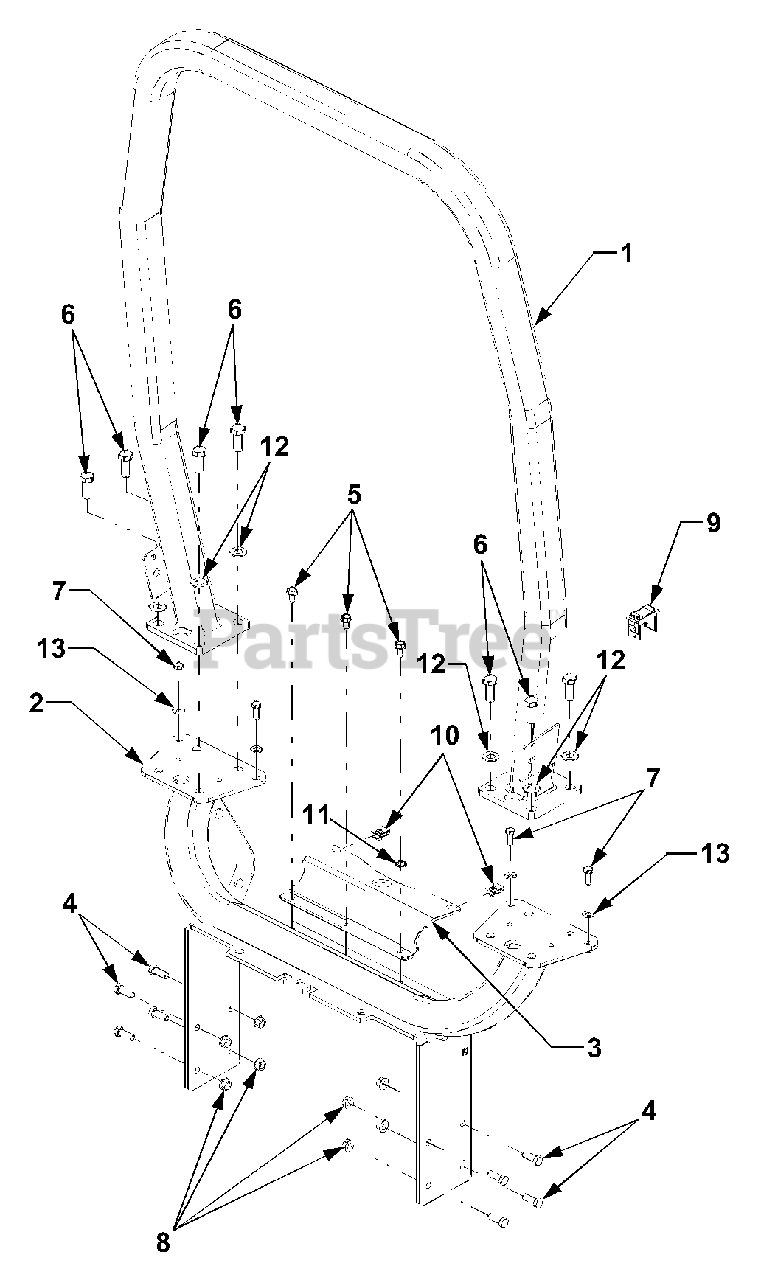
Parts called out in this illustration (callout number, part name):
3	Bracket, Rear Seat Mounting
4	Screw, Hex Cap, 3/8-16 x 1.0 GR5
5	Screw, Hex Wash. Hd. Tapp 5/16-18 x .75
6	Screw, Hex Cap, 1/2-13 x 1.25 GR5
7	Screw, Hex Cap, 5/16-18 x .875 GR5
8	Nut, Hex Flange Lock, 3/8-16 GRF
10	Nut, Speed, 5/16-18
11	Washer, Ext. Tooth Lock, 3/8
12	Washer, Flat, .51 x 1.0 x .060
13	Washer, Flat, .344 x .688 x .065
